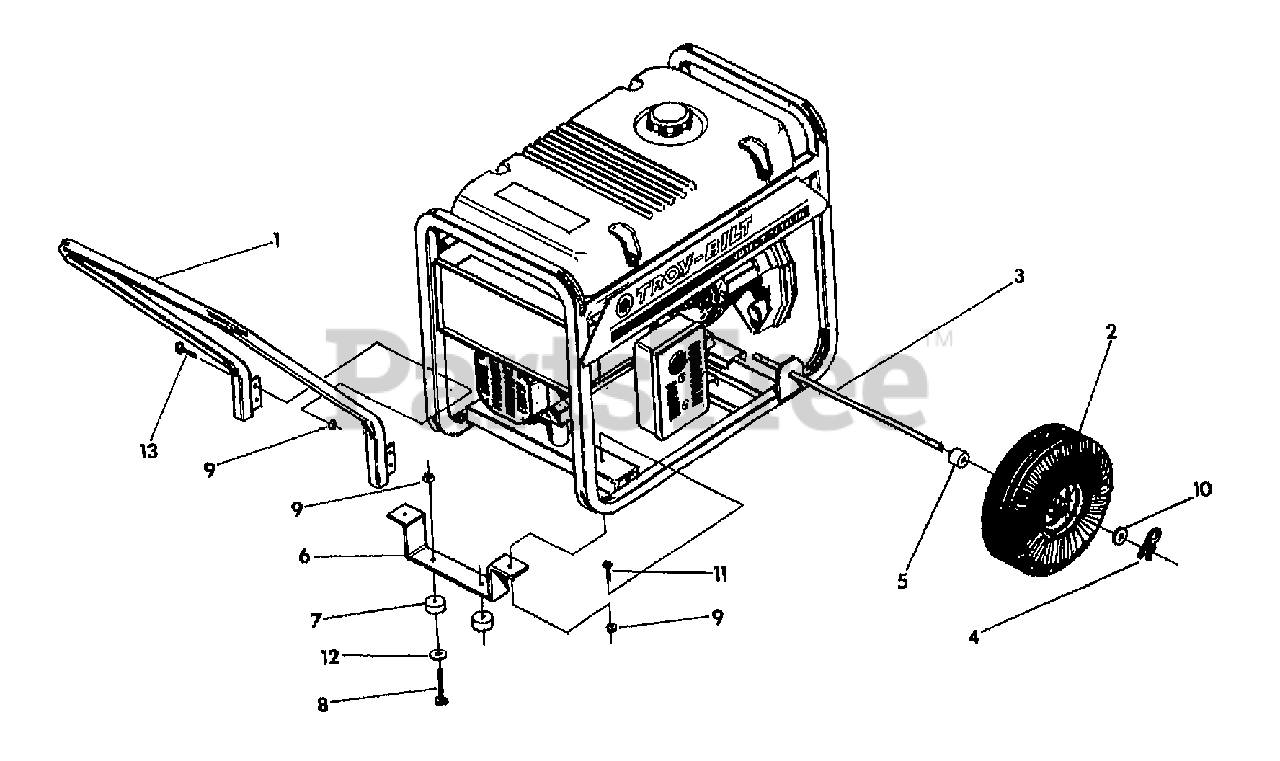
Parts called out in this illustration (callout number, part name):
1	HANDLE (6000W GENERATOR)
3	AXLE (6000W GENERATOR)
4	PIN-RETAINING
5	SPACER
7	MOUNT-VIBRATION
8	SCR-HH M8-1.25X30MM
9	NUT-HF/LK M8-1.25
10	WASHER-WHEEL (GENERATOR)
11	SCR-HH M8-1.25X20MM
12	WASHER-M8 VIBRATION MOUNT
13	SCR-CAP M8-1.25X45MM
